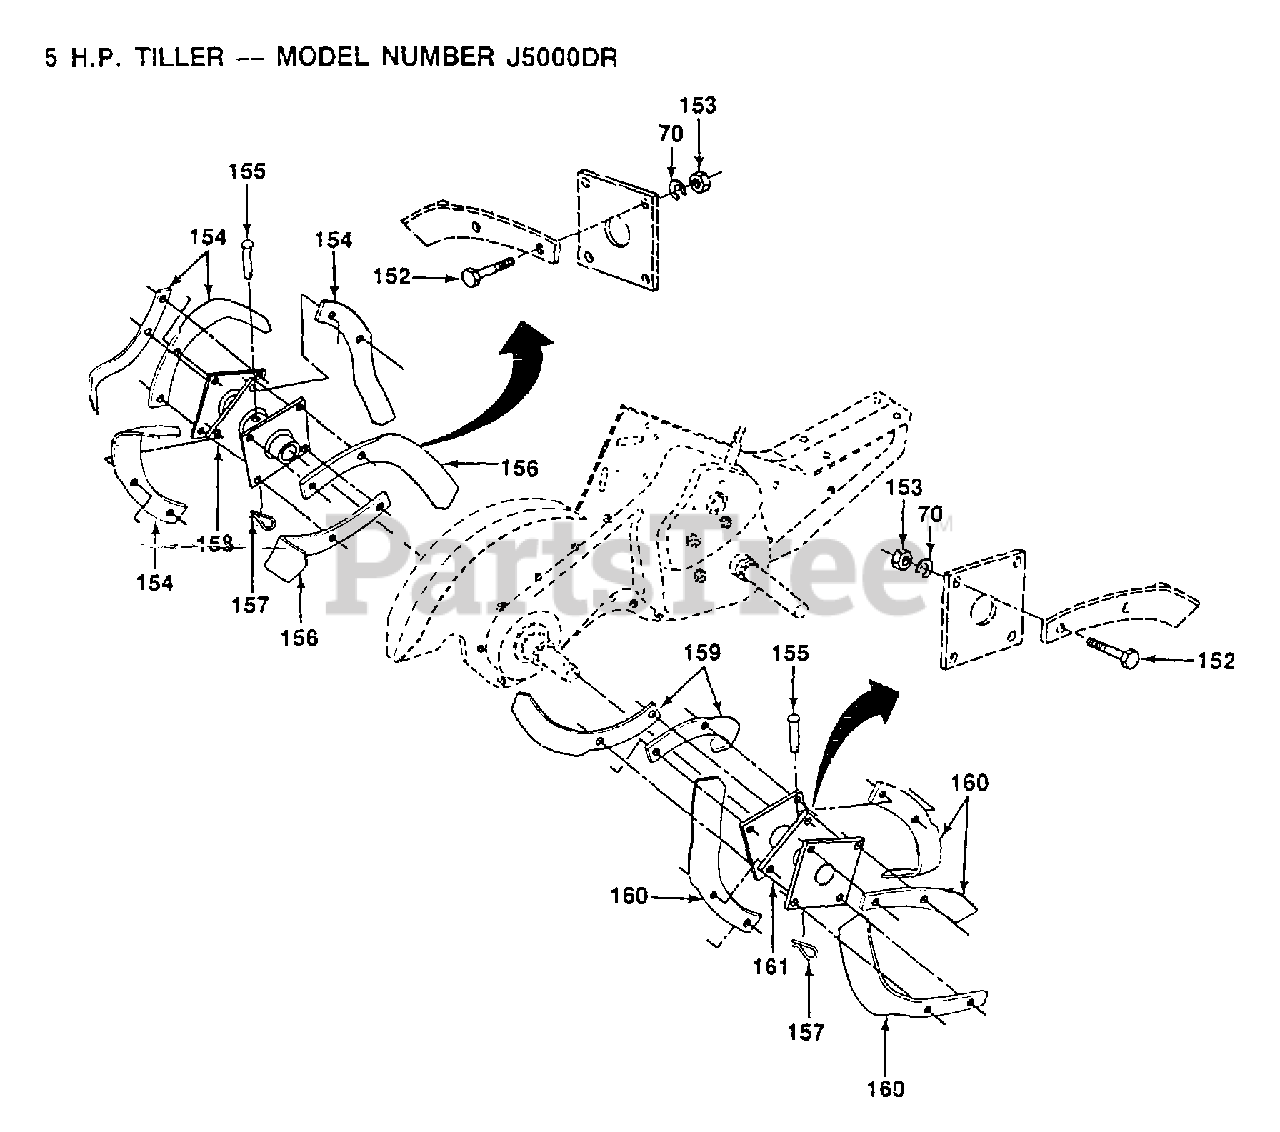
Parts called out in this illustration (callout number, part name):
152	BOLT
155	RIVET.PAN HD.1.75
156	"TINE.LH.12"""
157	RETAINER.SPRING
158	TINE ASSY LH CRT
159	"TINE.RH.12"""
161	TINE ASSY RH CRT
